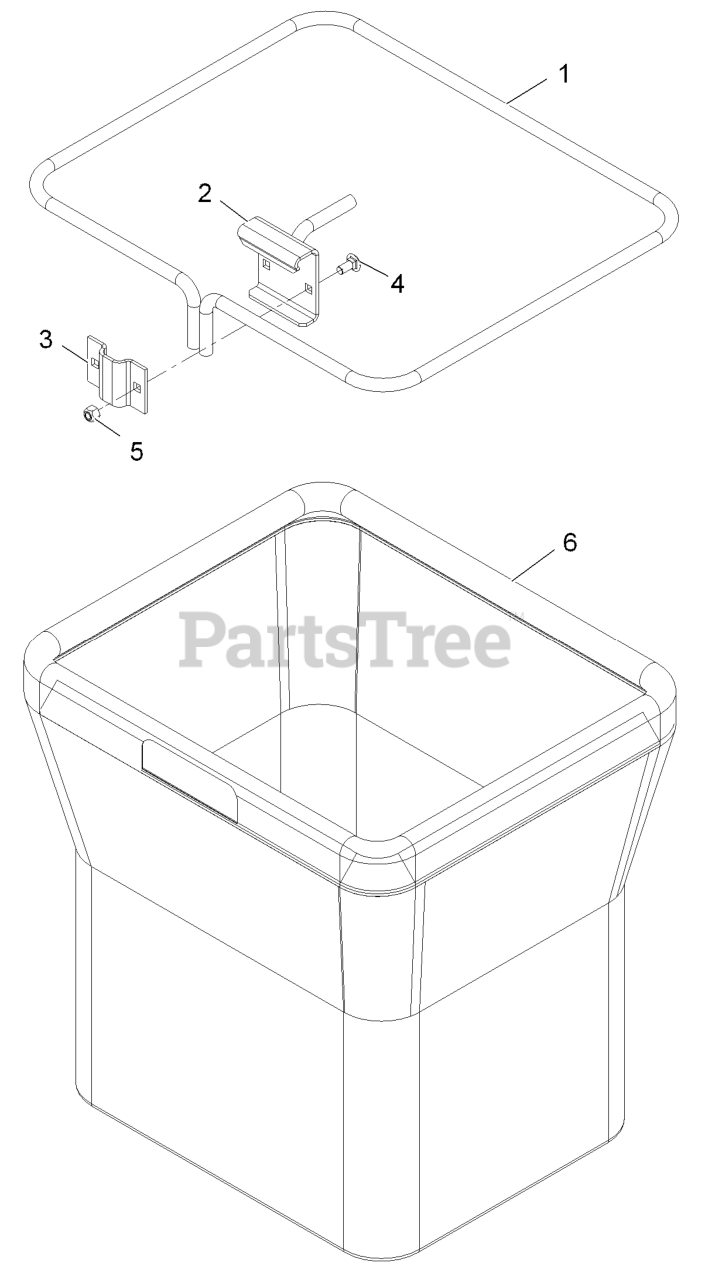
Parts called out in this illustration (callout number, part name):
1	FRAME-BAG
4	BOLT-CARR
5	NUT-LOCK, NI
6	BAG,20 IN. DEPTH
